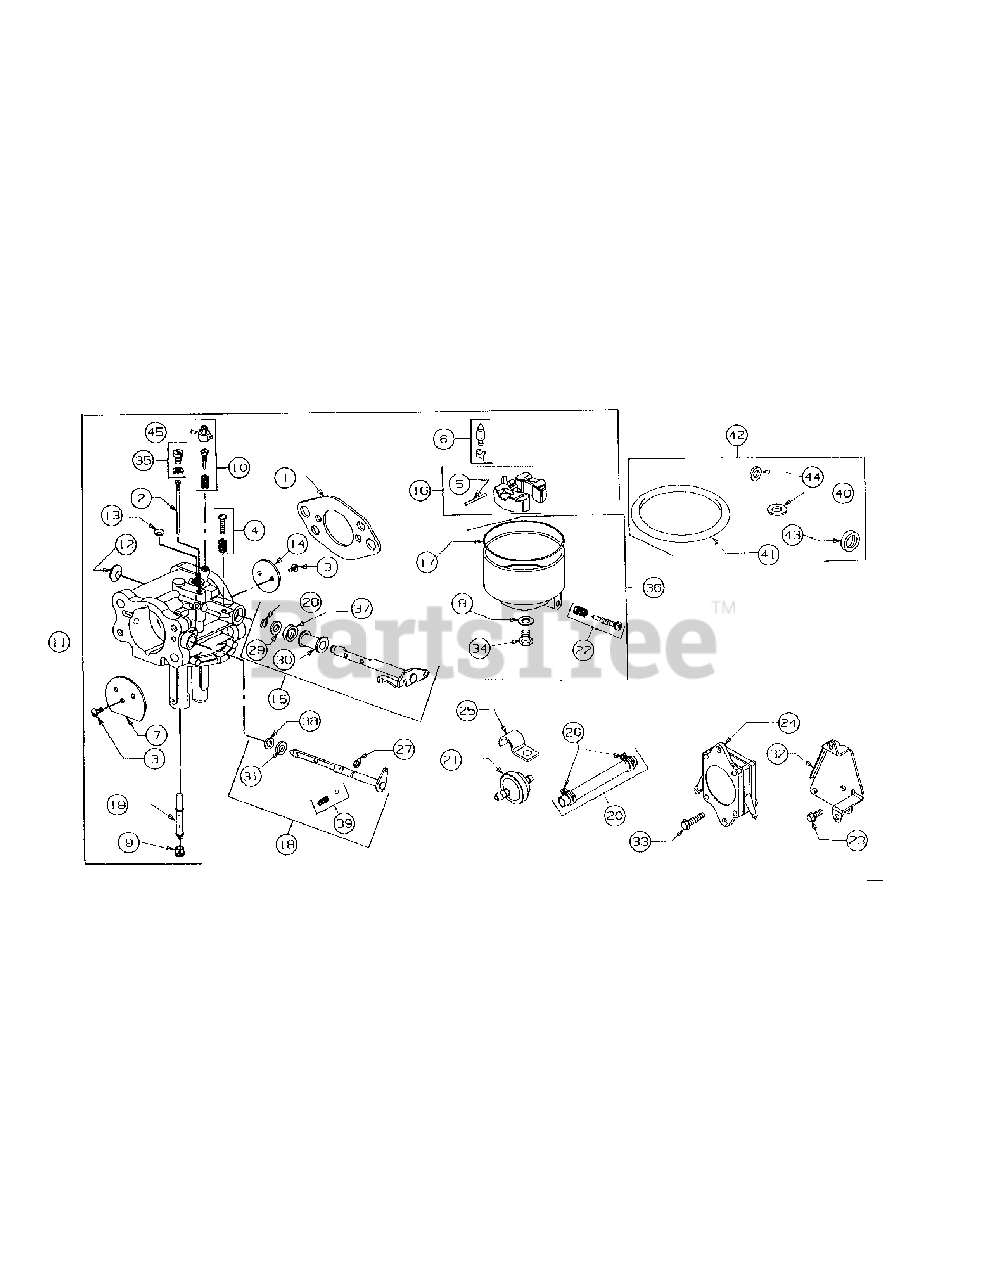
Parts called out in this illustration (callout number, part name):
1	Gasket, Carburetor Mtg
2	Nozzle, Carburetor
3	Screw, Valve Mtg
4	Screw, Throttle Adjusting
5	Pin, Float Hinge Pin
6	Valve, Fuel Inlet
7	Valve Choke
8	Gasket, Sealing
9	Jet, Main
10	Valve Assembly, Carburetor Idle
11	Carburetor Assembly
12	Plug, Welch
13	Plug, Welch
14	Valve, Throttle
15	Shaftm Throttle
16	Float Assembly, Carburetor
17	Gasket Bowl
18	Shaft, Choke
19	Nozzle
20	Hose, Fuel, 11''
20	Hose, Fuel, 23''
21	Filter, Fuel
22	Drain, Carburetor Bowl
23	Screw, Sem
24	Pump, Fuel
25	Clamp, Fuel Hose
26	Clamp, Hose
27	Retainer, Choke Shaft
28	Retainer, Throttle Shaft
29	Collar, Throttle
30	Collar, Throttle
31	Collar, Choke
32	Bracket, Fuel Pump
33	Screw, Mtg
34	Screw, Bowl Mtg
35	Plug & Seal, Carburetor
36	Bowl Assembly, Float
37	Seal, Throttle Shaft
38	Seal, Choke Shaft
39	Ball, Choke Locator
40	Gasket, Sealing
41	Gasket, Bowl Mtg
42	Gasket Set, Carburetor
43	Seal, Throttle Shaft
44	Seal, Choke Shaft
45	Cap, Limiter
